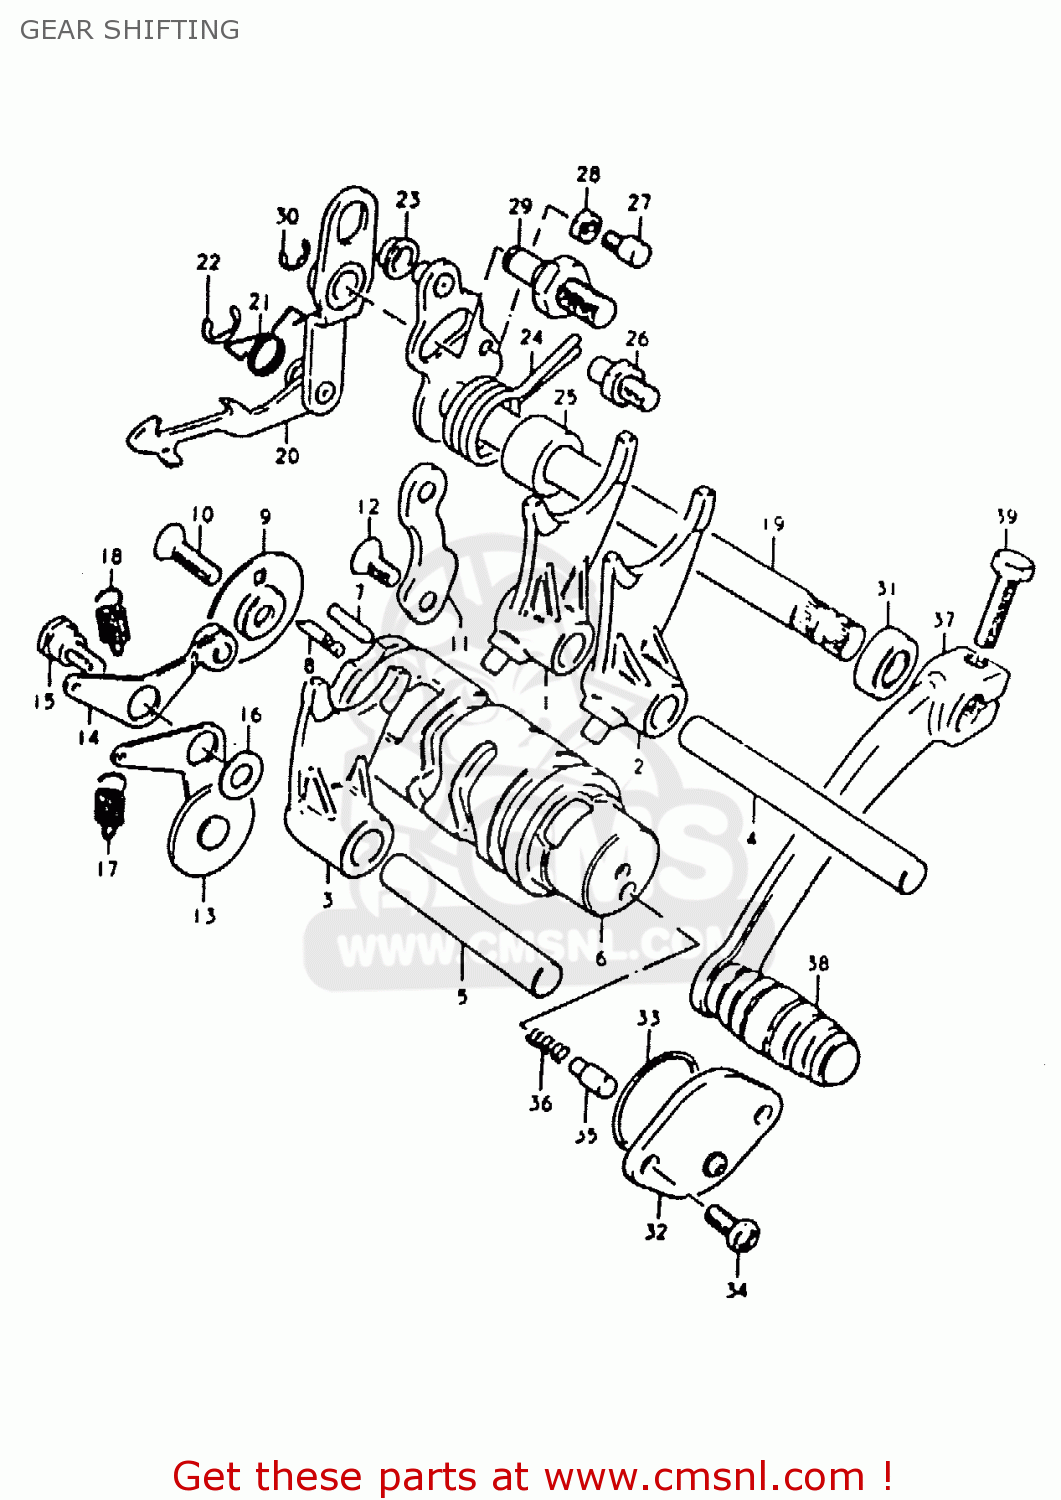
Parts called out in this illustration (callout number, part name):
1	FORK,GEAR SHIFT NO.1
2	FORK,GEAR SHIFT NO.2
3	FORK,GEAR SHIFT NO.2
4	SHAFT, GEAR SHIFTING NO.1
5	SHAFT,GEAR SHIFT FORK
6	CAM,GEAR SHIFT
7	PIN(4X15.8)
8	PIN
9	RETAINER,GEAR SHIFT CAM DR PIN
10	SCREW
11	GUIDE,GEAR SHIFT CAM
12	SCREW
13	STOPPER,GEAR SHIFT CAM
14	STOPPER,GEAR SHIFT CAM NEUTRAL
15	BOLT(6X18.3)
16	WASHER
17	SPRING
18	SPRING
19	SHAFT,GEAR SHIFT
20	PAWL,GEAR SHIFT
21	SPRING
22	E RING
23	SPACER(7X10X5)
24	SPRING
25	SPACER(12X20X15.3)
26	STOPPER,GEAR SHIFT CAM
27	BOLT,GEAR SHAFT RETURN SPR SET
28	NUT 6MM
29	STOPPER,GEAR SHIFT CAM
30	E RING 6MM
31	OIL SEAL
32	BODY,GEAR SHIFT SWITCH
33	O-RING (D:2.4 ID:26.2)
34	SCREW
35	PIN(5X15.5)
36	SPRING
37	LEVER ASSEMBLY,GEAR SHIFTING
38	RUBBER,GEAR SHIFT PEDAL
39	BOLT
